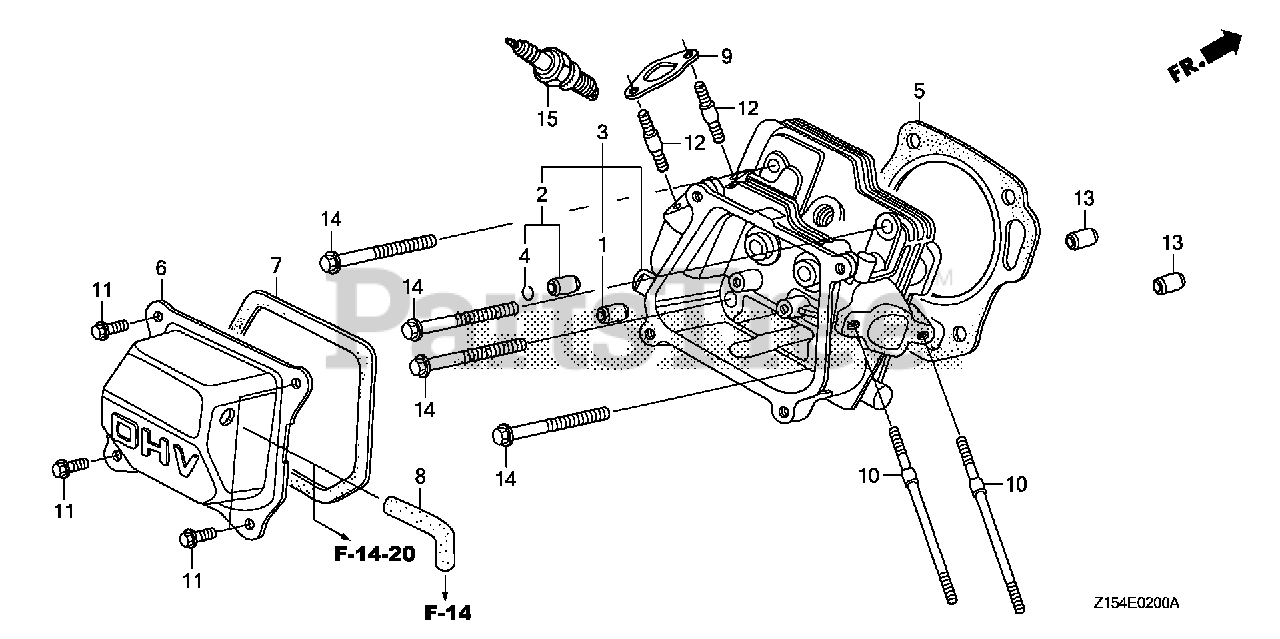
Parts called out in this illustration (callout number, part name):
1	GUIDE, VALVE (OVER SIZE)
2	GUIDE, EX. VALVE (OVER SIZE)
3	CYLINDER HEAD
4	CLIP, VALVE GUIDE
5	GASKET, CYLINDER HEAD (GUANGZHOU LEAKLESS)
5	GASKET, CYLINDER HEAD (NINGBO SIL GASKET)
6	COVER, HEAD
7	GASKET, HEAD COVER (NINGBO SIL GASKET)
7	GASKET, HEAD COVER
8	TUBE, BREATHER
9	GASKET, MUFFLER
9	GASKET, MUFFLER (NINGBO SIL GASKET)
10	BOLT, STUD (6X104) (CT200)
11	BOLT, FLANGE (6X12) (CT200)
12	BOLT, STUD (8X32)
13	PIN, DOWEL (10X16)
14	BOLT, FLANGE (8X60)
15	SPARK PLUG (BPR5ES) (NGK)
15	SPARK PLUG (W16EPR-U) (DENSO)
15	SPARK PLUG (BPR6ES) (NGK)
15	SPARK PLUG (W20EPR-U) (DENSO)
